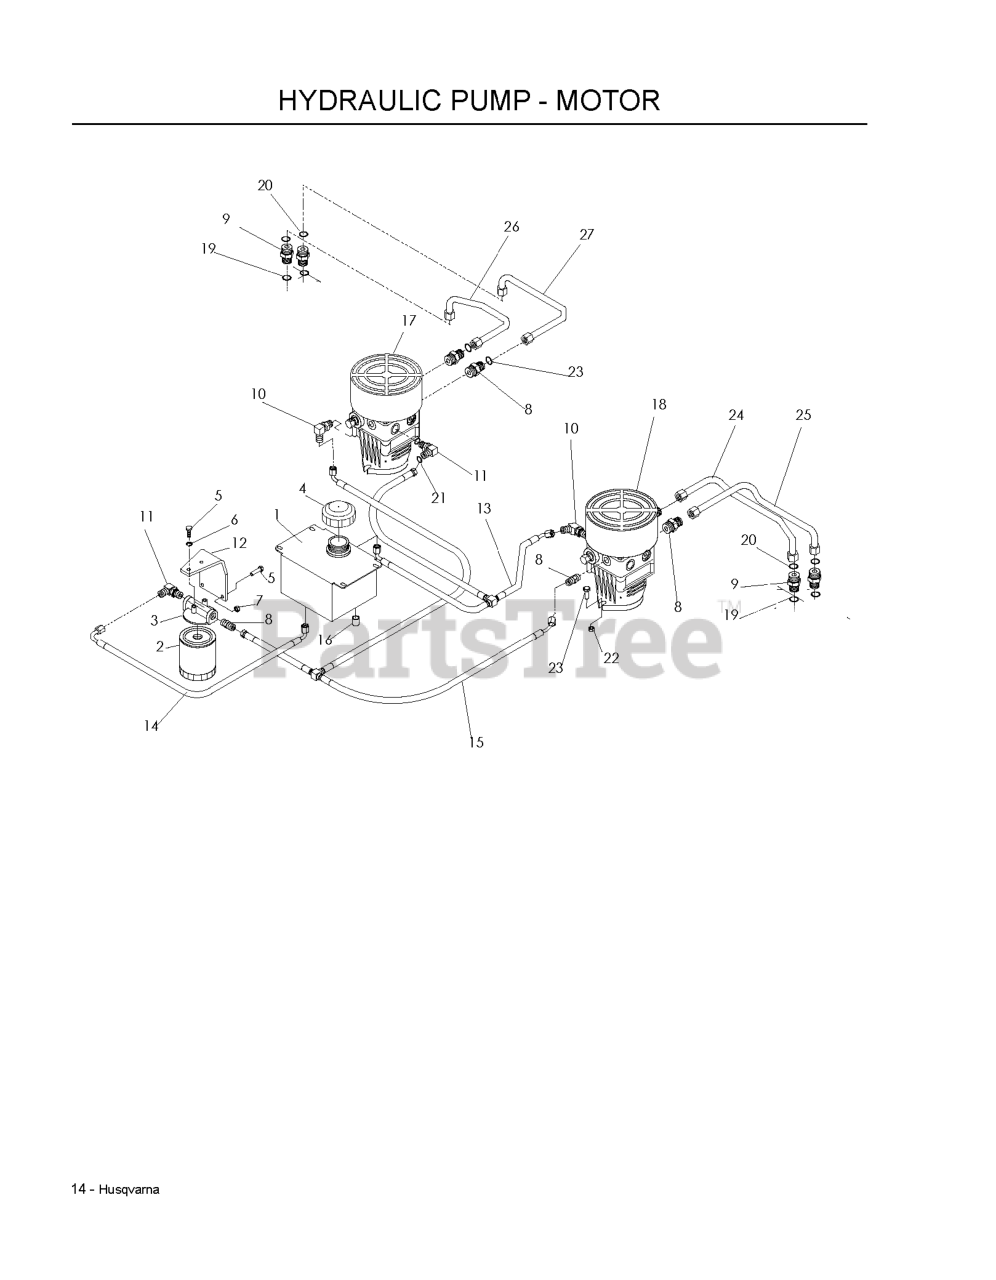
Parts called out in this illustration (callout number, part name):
2	HYDRAULIC OIL FILTER
3	FILTER HEAD
4	HYDRAULIC CAP
5	HCS 1/4C X 3/4 HCS
6	LOCKWASHER 1/4"
7	NUT.1/4-20.HEX.NYLOC.ZD
8	HYDRAULIC FITTING
10	45 DEG ADJ ELBOW
11	ELBOW, F6801-6-6-0 90 DEGREE
12	OIL FILTER BRKT
13	HOSE, T-ASM RETURN
14	HOSE, TANK - FILTER LINE
15	HOSE, T-ASM SUPPLY
16	NUT 9/16-18 JIC CAP
17	HG_PUMP, 10CC W/FAN RIGHT
18	HG_PUMP, 10CC W/FAN LEFT
22	NUT 3/8C CENTERBLOCK
23	4CS 3/8C X 1 SERRATED HEAD
24	HOSE, RPA - MA LINE
25	HOSE, RPB - MB LINE
26	HOSE, LPA - MB LINE
27	HOSE, LPB - MA LINE
